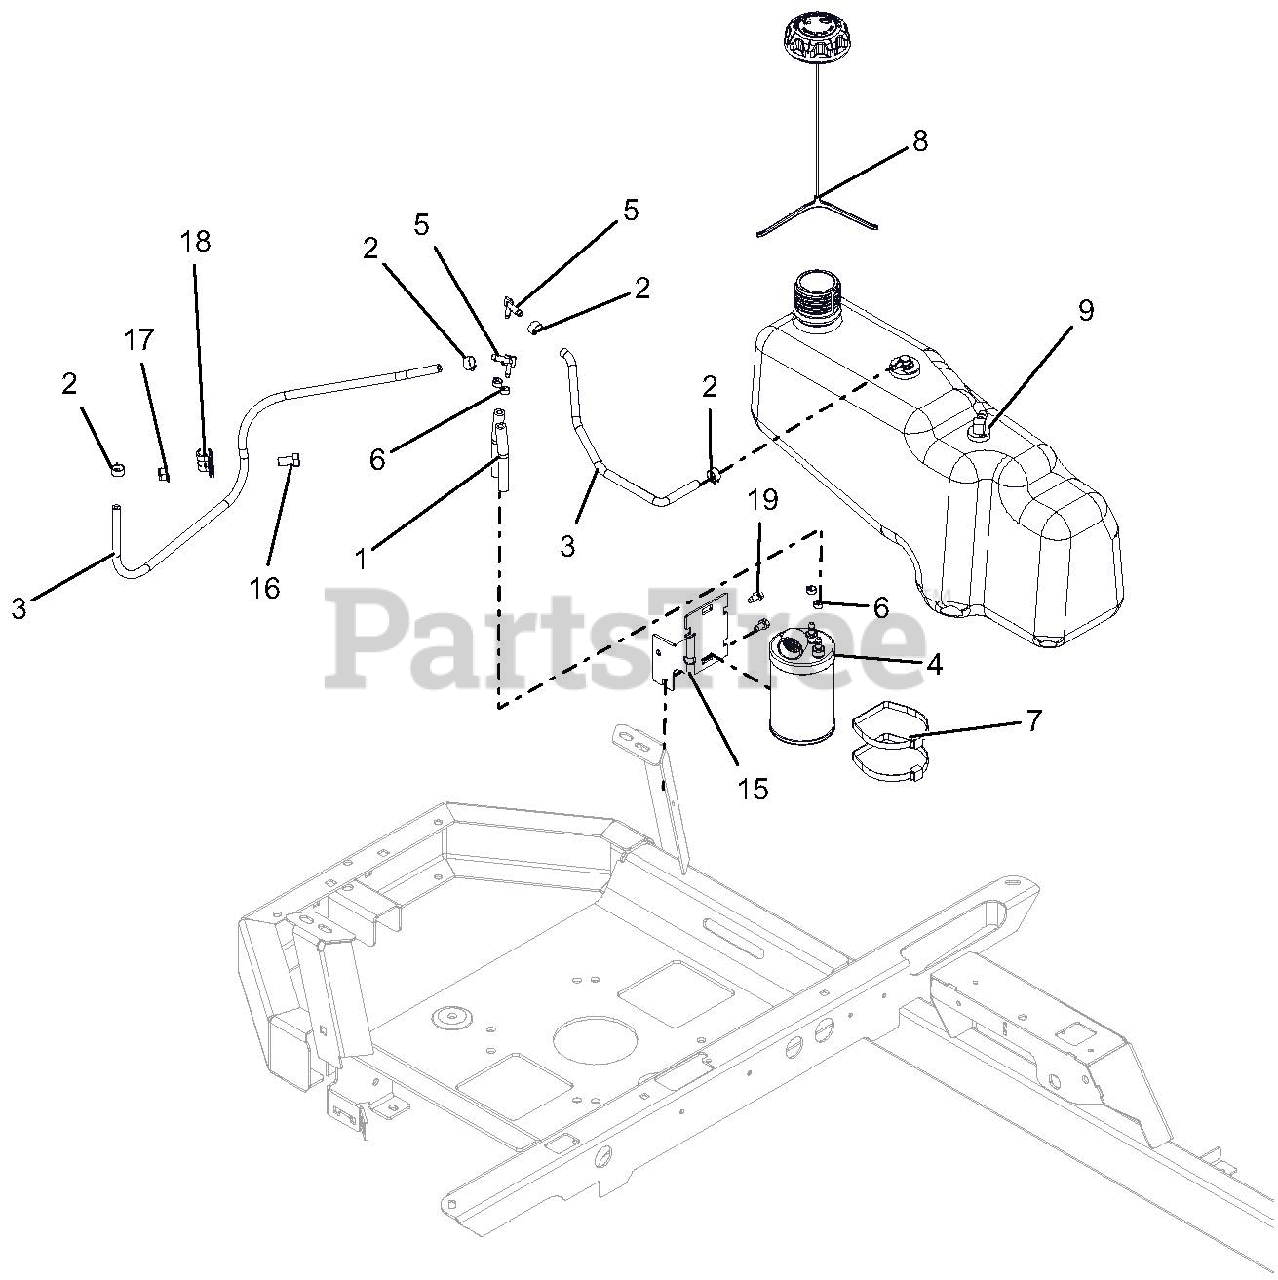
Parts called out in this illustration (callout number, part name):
1	HOSE, .25 LOW-PERM BULK GAS-5.0" LONG
2	CLAMP, FUEL LINE
3	HOSE, .188 LOW
4	CARBON CANISTER, 300CC
5	FITTING-3/16X1/4 90DEGREE VAC
6	CLAMP - HOSE, SPRING .188
7	P-PLASTIC TIE STRAP LARGE
8	CAP, FUEL VENT-IN 2.25" RATCHET
9	ASM, TANK NON-PERM FUEL
15	BRKT, MOUNT -CARB CANISTER-BLACK
16	BLT-HEX .38-16X.75 GR5 YWZC
17	NUT-LK-NYL-FLG .38-16 YWZC
18	CLAMP, CUSHIONED STEEL
19	SCR-TAP .25-20X.50 HWH TR YWZ
